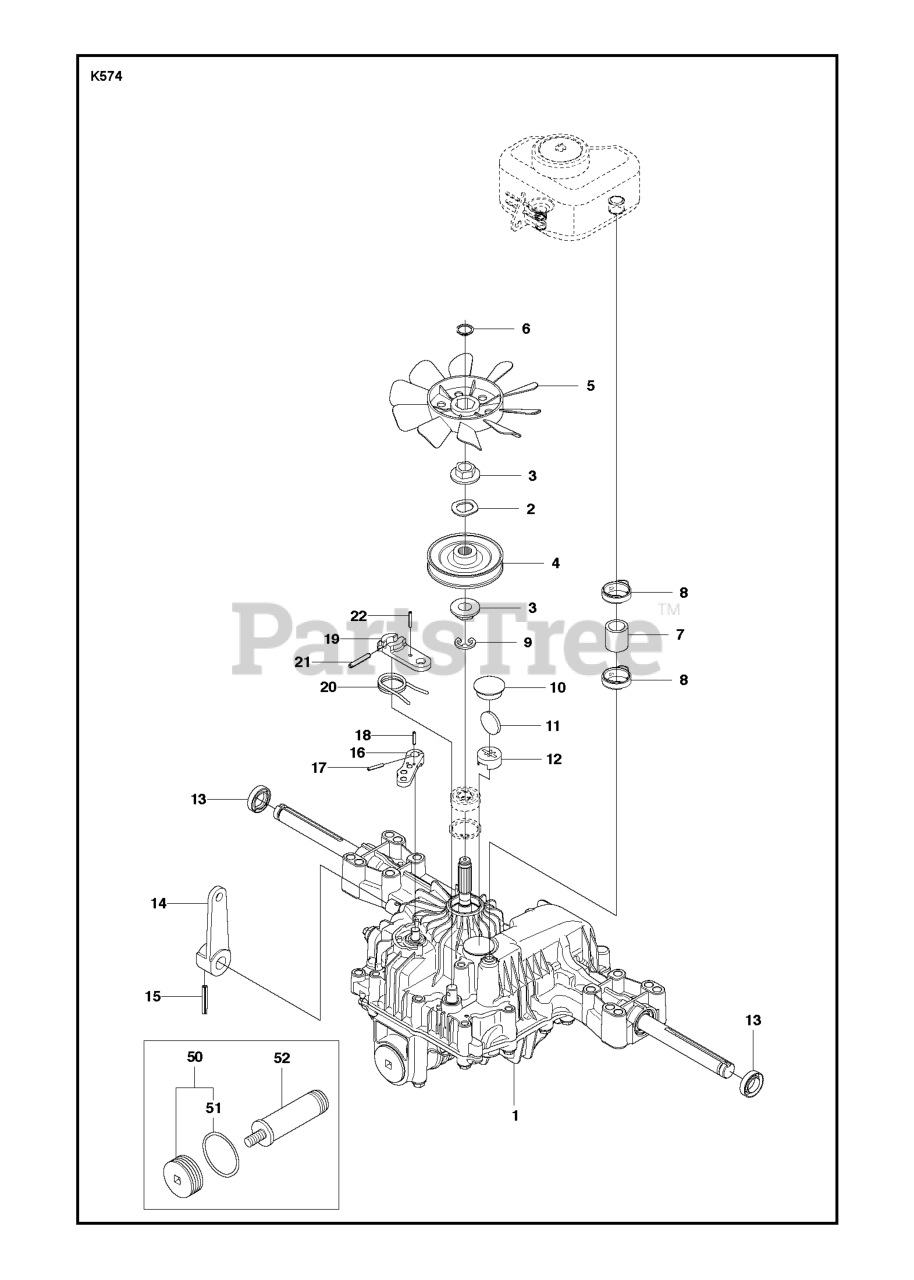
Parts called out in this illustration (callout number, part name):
1	TRANSMISSION K574A
5	FAN.BLACK.1A646083070
6	RETAINING RING **
8	CLAMP
12	MAGNET HOLDER
13	RP SEAL.19, 19216334280
14	CONTROL LEVER
20	RETURN SPRING
52	FILTER
